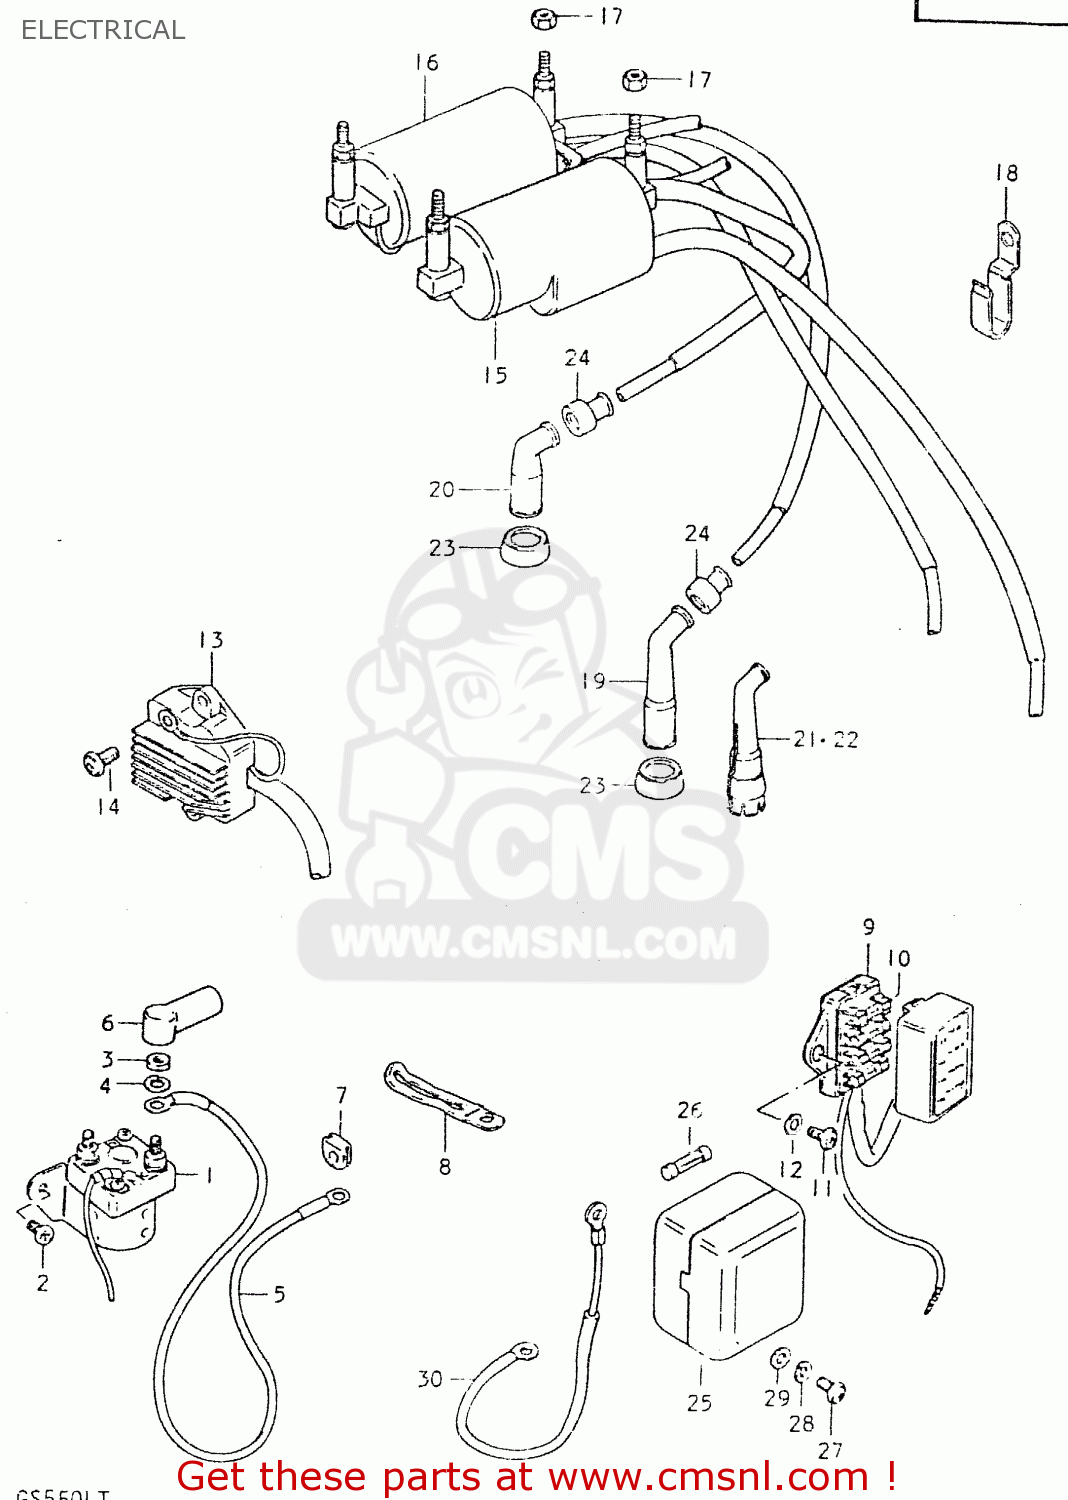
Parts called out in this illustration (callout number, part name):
1	RELAY ASSY,STARTING MOTOR
2	SCREW
3	NUT 6MM
4	LOCK WASHER
5	WIRE,STARTER MOTOR LEAD
6	CAP,STARTER RELAY
7	GROMMET,STARTER CABLE
8	CLAMP
9	BOX ASSEMBLY,FUSE
10	FUSE(15A)
11	SCREW 6X12
12	WASHER
13	RECTIFIER ASSEMBLY
14	SCREW
15	COIL ASSEMBLY,IGNITION
16	COIL ASSEMBLY,IGNITION
17	NUT
18	CLAMP
19	CAP ASSY,SPARK PLUG
20	CAP,SPARK PLUG
21	CAP,SPARK PLUG
22	CAP, SPARK PLUG (S)
23	SEAL,SPARK PLUG
24	SEAL,SPARK PLU
25	TERMINAL ASSEMBLY,POWER SO
26	FUSE(10A)
27	SCREW
28	LOCK WASHER
29	WASHER
30	WIRE,POWER SOURCE LEAD
